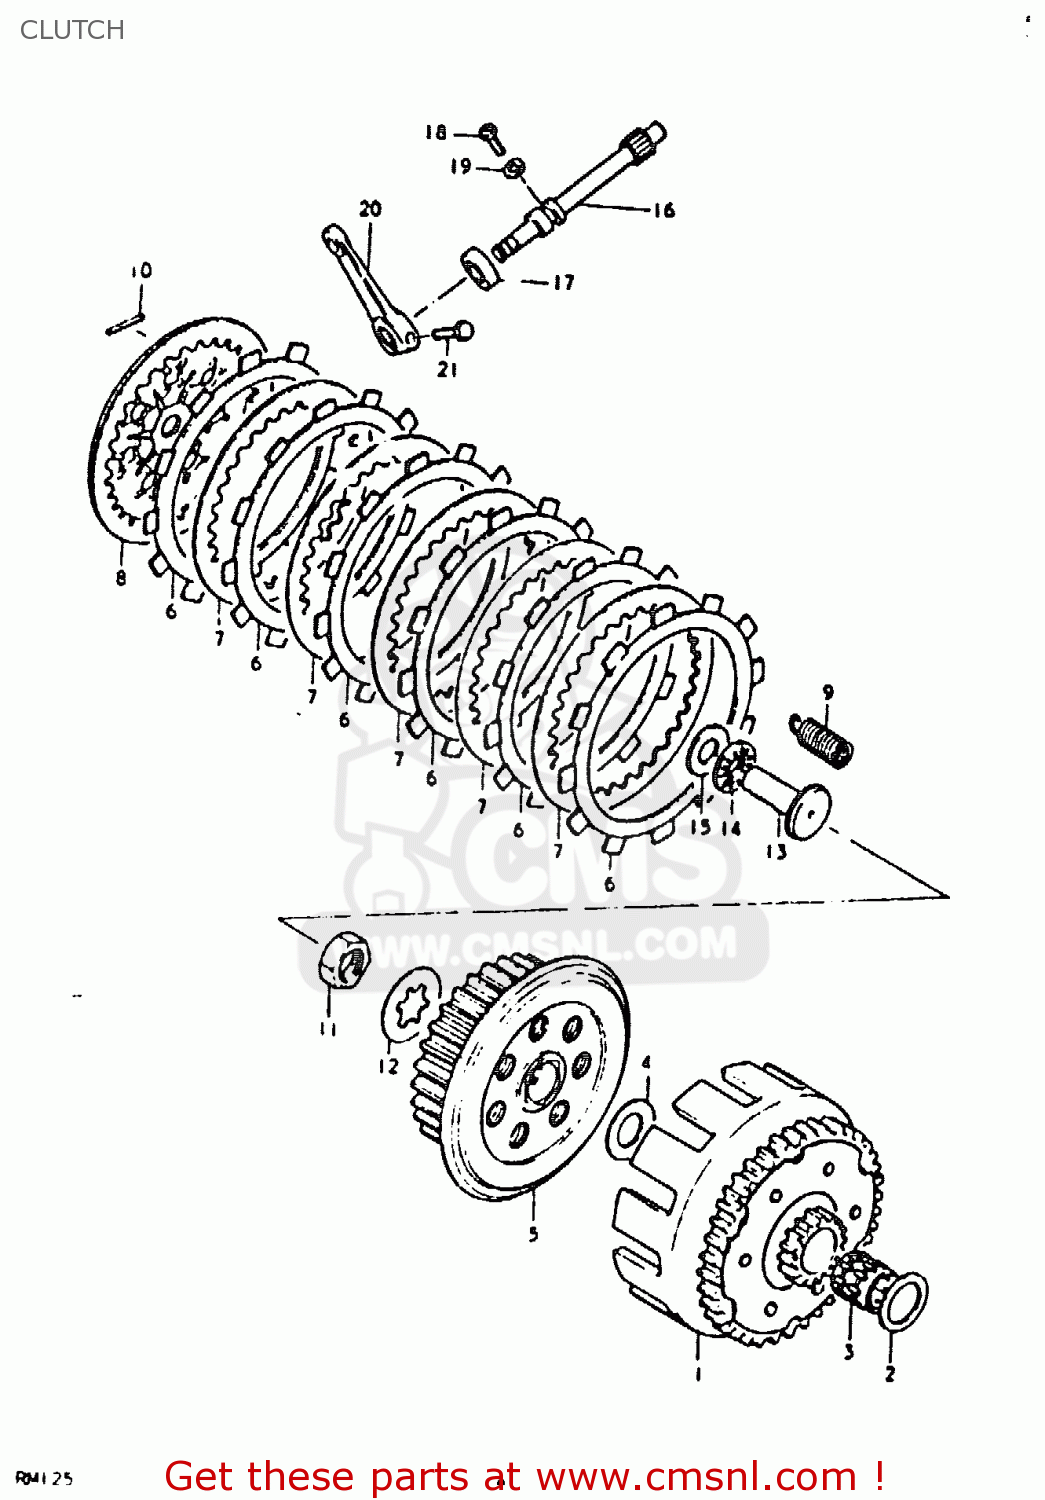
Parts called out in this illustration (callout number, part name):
1	GEAR ASSEMBLY,PRIMARY DRIVE
2	WASHER
3	BEARING(20X25X26)
4	WASHER
5	HUB,CLUTCH SLEEVE
6	PLATE,CLUTCH DRIVE
7	PLATE,CLUTCH DRIVEN
8	PLATE,CLUTCH PRESSURE
9	SPRING
10	PIN(2.5X19.8)
11	NUT
12	WASHER,LOCK
13	RACK,CLUTCH RELEASE
14	BEARING(10X22X2.8)
15	WASHER(10.1X21.4X0.8)
16	PINION, RELEASE
17	SEAL,OIL (10X17X5)
18	BOLT(6X12)
19	WASHER
20	ARM,CLUTCH RELEASE
21	BOLT, UPPER
